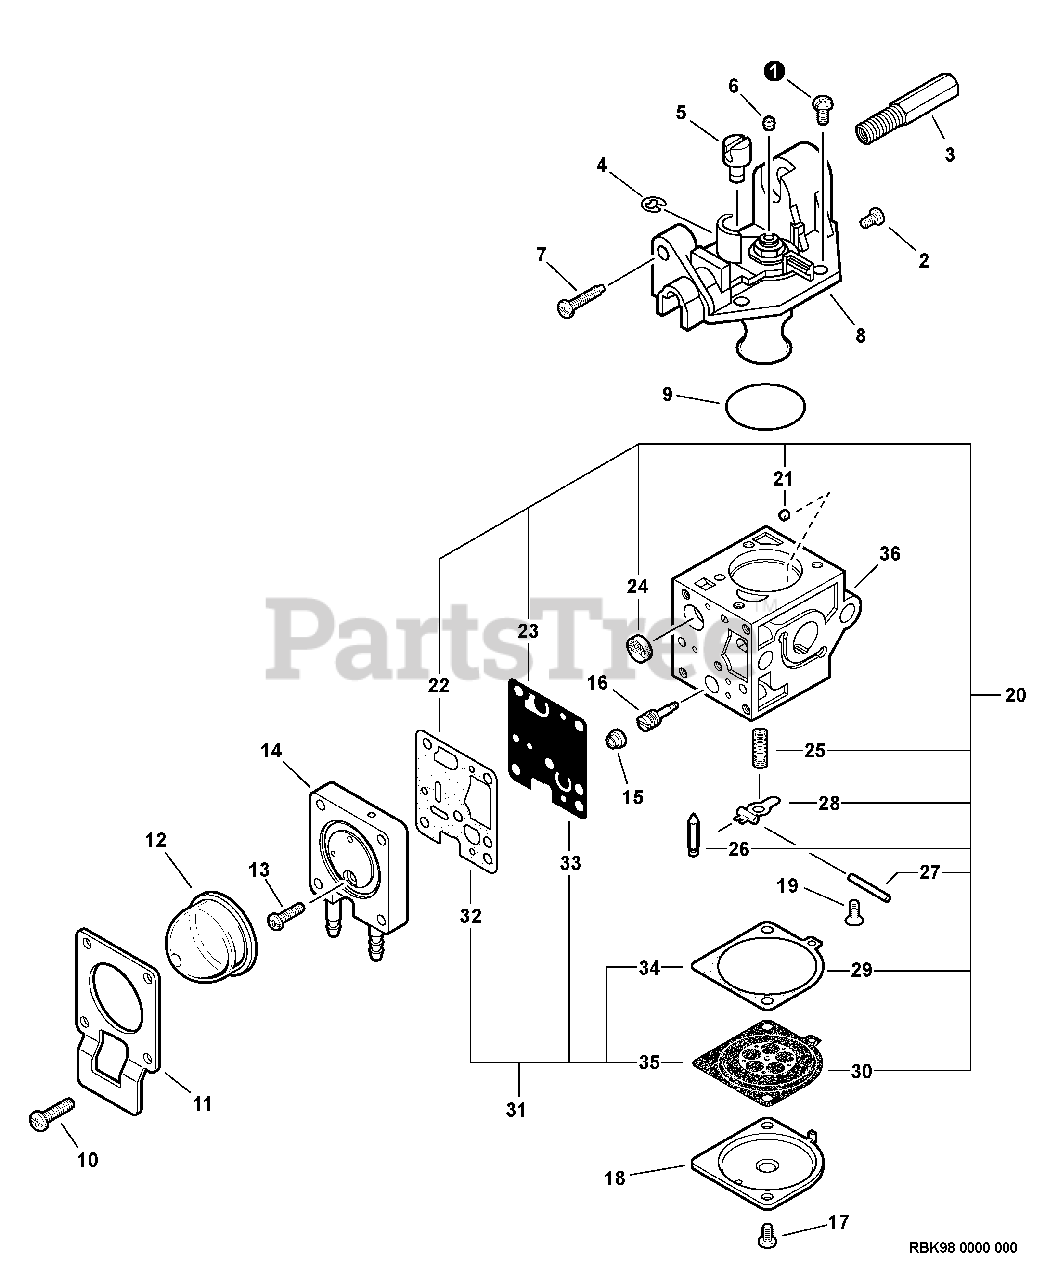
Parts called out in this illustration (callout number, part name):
3	ADJUSTER, THROTTLE CABLE
5	SWIVEL
7	SCREW, IDLE ADJUST
8	COVER ASSY, ROTOR
11	RETAINER, PURGE BULB
12	BULB, PURGE
14	COVER ASSY, ROTOR
15	CAP, LIMITER
16	NEEDLE, HIGH SPEED
18	COVER, METERING DIAPHRAGM
20	REPAIR KIT
21	GUIDE, ROLLER
22	GASKET, PUMP
23	DIAPHRAGM, PUMP
24	STRAINER
25	SPRING, METERING LEVER
26	VALVE, INLET NEEDLE
27	PIN, METERING LEVER
28	LEVER, METERING
29	GASKET, DIAPHRAGM
30	DIAPHRAGM, METERING
31	GASKET / DIAPHRAGM KIT
32	GASKET, PUMP
33	DIAPHRAGM, PUMP
34	GASKET, DIAPHRAGM
35	DIAPHRAGM, METERING
36	BODY, CARBURETOR
